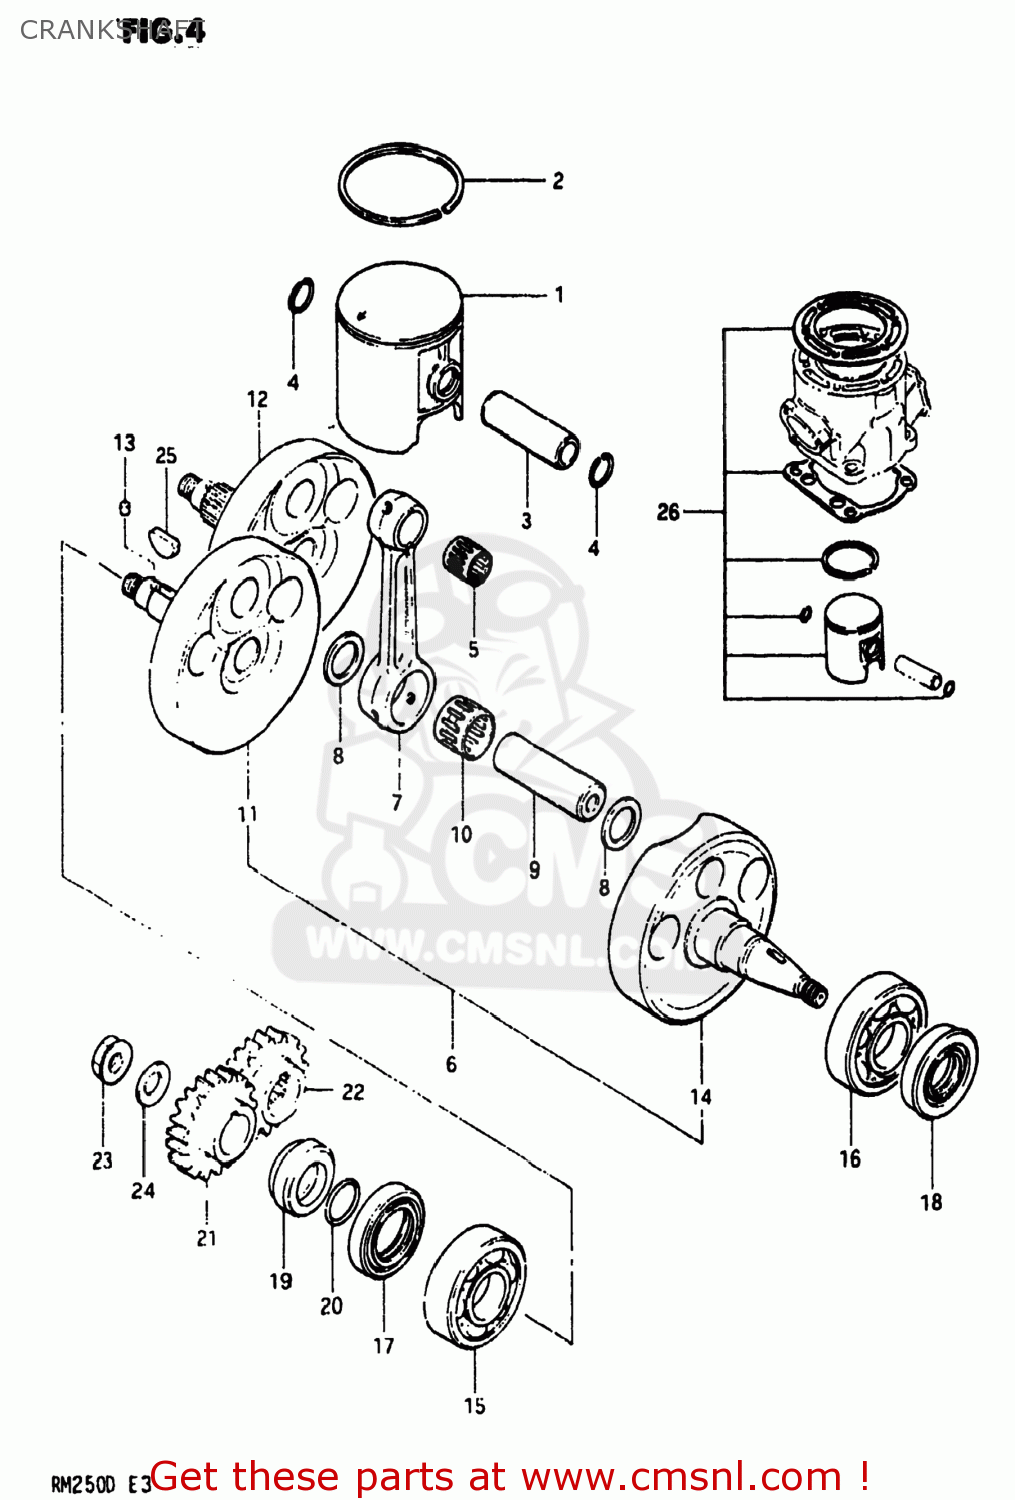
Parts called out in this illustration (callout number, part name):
1	PISTON
2	RING,PISTON
3	PIN,PISTON (18MM)
4	CIRCLIP
5	BEARING(18X23X22)
6	CRANKSHAFT ASSEMBLY
7	ROD,CONNECTING
8	WASHER(24X29X1.5)
9	PIN,CRANK
10	BEARING
11	CRANKSHAFT
12	CRANKSHAFT
13	PIN 3X5
14	CRANKSHAFT,LEFT
15	BEARING
16	BEARING
17	SEAL,OIL(36X52X8)
18	SEAL,OIL(19.6X37X8)
19	SPACER,PRIMARY DRIVE GEAR
20	O RING(D:2.4,ID:21.8)
21	GEAR,PRIMARY DRIVE
22	GEAR,PRIMARY DRIVE
23	NUT
24	WASHER
25	KEY
26	PISTON SET
